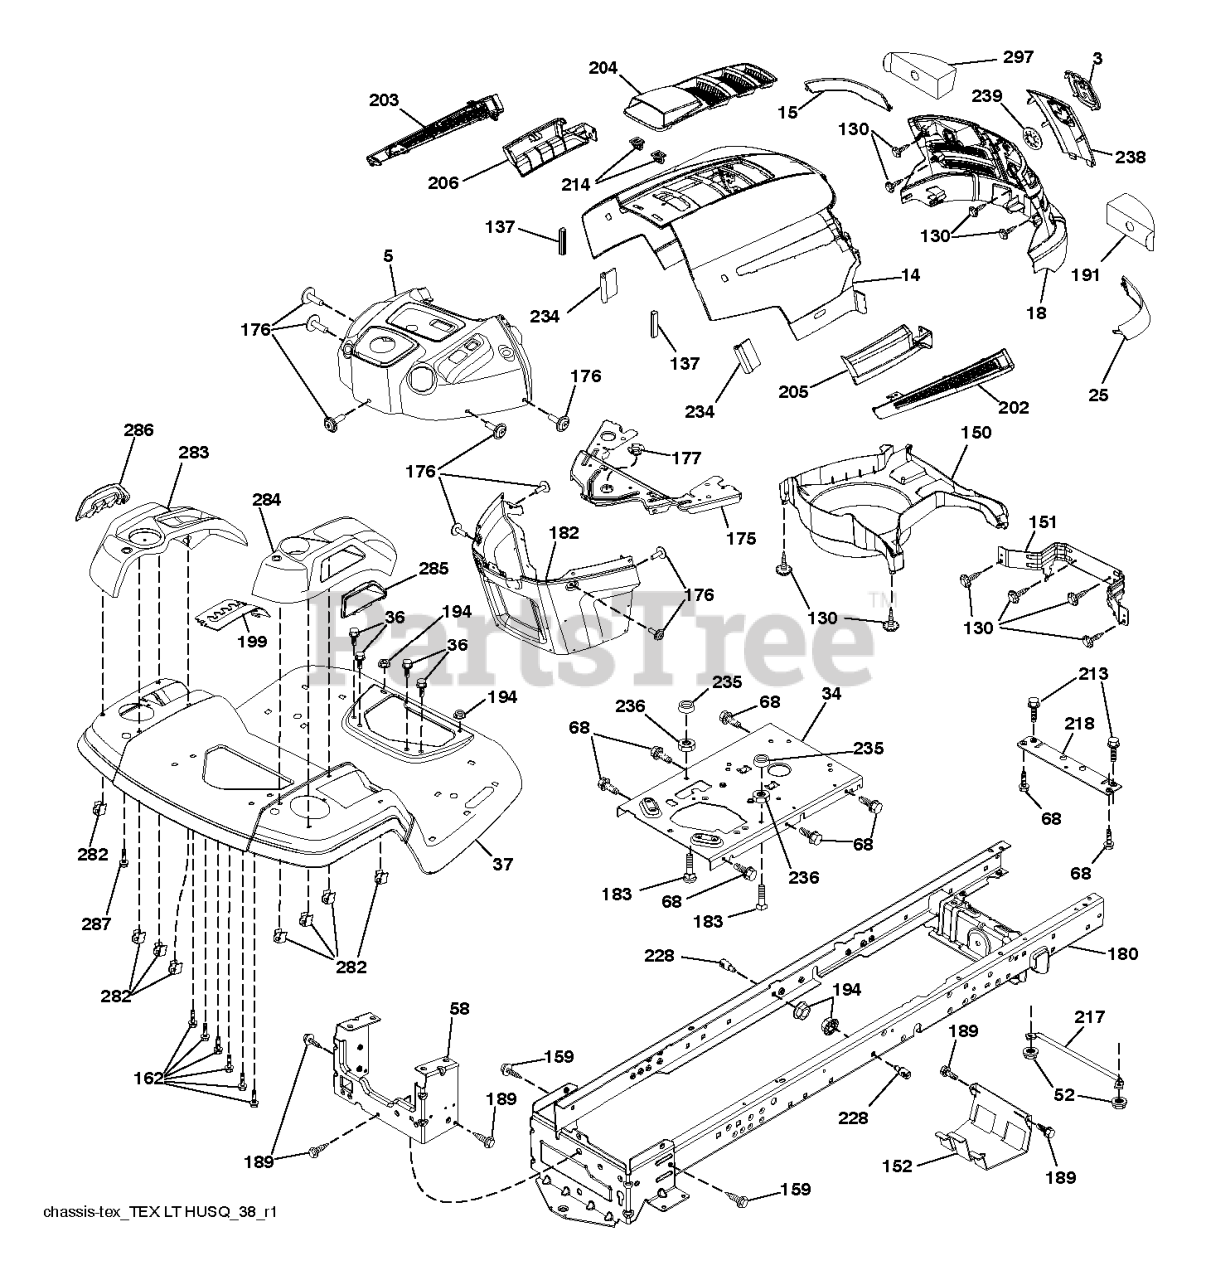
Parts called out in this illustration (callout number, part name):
3	RP LOGO
5	DASH
14	HOOD.HUSQVARNA.LT.ORANGE
15	LENS.HUSQVARNA LT.LH
18	GRILLE.SVC.HUSQVARNA.LT.GREY
25	LENS.HUSQVARNA LT.RH
34	PLATE.ENGINE.WELDED.CHASSIS
36	SCREW 5/16"
37	FENDER.TLT.FS.W/CUPHLD.ORANGE
52	LOCKNUT
58	DRAWBAR UPPER 2PC SMALL FENDER
68	Screw 5/16-18 x 1/2 Hex, Self Tapping 5/16-18 x 1/2
130	SCREW.#10 X 0.750.BOS
137	BUMPER DASH
151	BRACKET PIVOT
152	SHIELD.BROWNING.W/TEX
159	SCREW, 3/8-16X3/4
162	SCREW.HI-LO.CONSOLE
175	CROSSMEMBER
176	SCREW.#10-24X5/8.RN.QU
177	BUSHING STEERING
180	CHASS.WLDMNT.TL.12GA/2P.48/54
182	DASH.LOWER.PREDATOR LT
183	BOLT.5/16-18X1-1/4 FULL.THREAD
189	SCREW
191	INSERT.REFLECTIVE.RH.
194	NUT LOCK HEX FLANGE 5/16-18
199	PLATE.DECK.LIFT.HUSQ.LT
202	VENT SIDE HOOD LH
203	VENT SIDE HOOD RH
204	VENT TOP HOOD
205	SKIRT SIDE RH
206	SKIRT SIDE LH
213	BOLT
214	CLIP.RETAINER.TINNER.
217	ROD.PIVOT.HOOD
218	X-PIECE.HOOD.STOP.NON/
228	STUD.FASTNER.W/ANTI-ROTATE
234	BUMPER.HOOD.TEX.HUSQVARNA
235	SPACER FENDER
236	NUT.CENTERLOCK.5/16-
238	TRIM
282	CLIP.RETAINER.CONSOLE.LT.HUSQ
283	CONSOLE.DECK.LIFT.HUSQ.N/FR.GR
284	CONSOLE.SHFT.HYD,HUSQL
285	CONSOLE INSERT RH
286	CONSOLE.INSRT.LH.HUSQ.LT.BLACK
287	SCREW 1/4X20
297	INSERT REFLECTIVE
